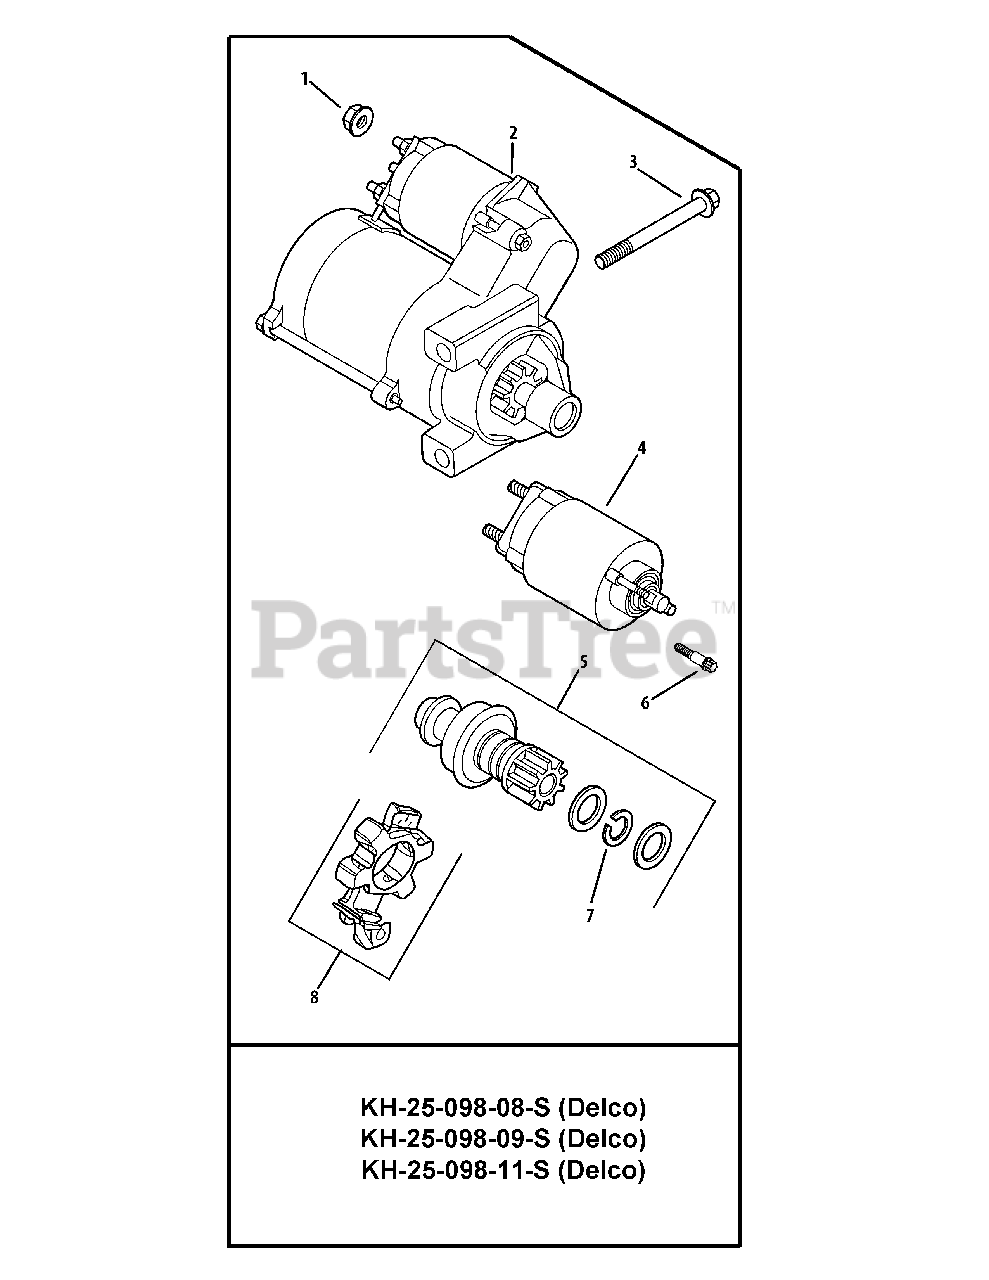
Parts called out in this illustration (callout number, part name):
1	Flange Nut, M8 x 1.25
2	Electric Starter (Solenoid Shift)
3	Flange Screw, M8 x 1.25 x 80
5	Starter Pinion Kit
6	External Torx Head Screw
7	Retaining Ring
8	Brush Holder Kit
